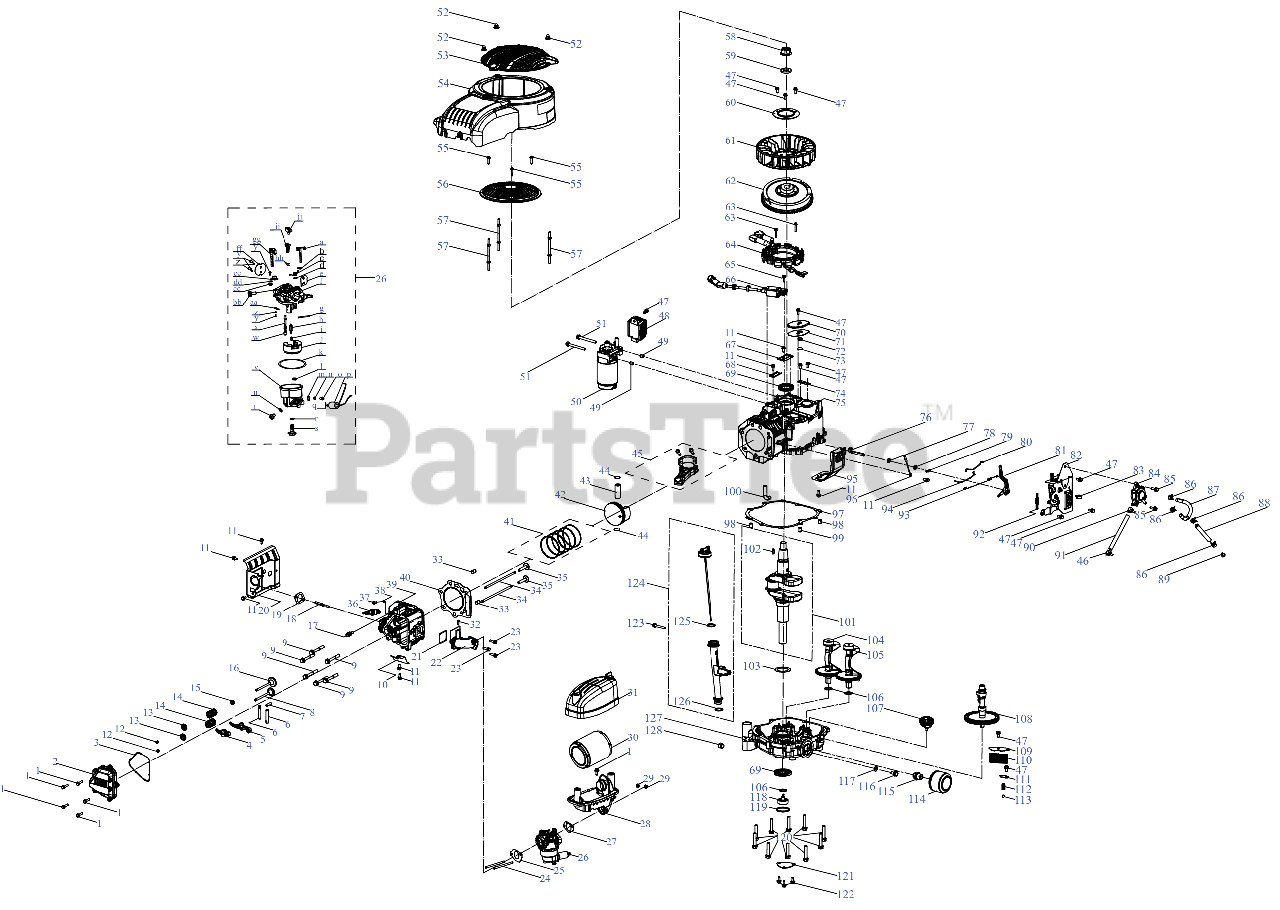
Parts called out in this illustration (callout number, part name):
1	BOLT M6-1 x 25 GR8.8
2	VALVE COVER
3	VALVE COVER GASKET
4	ROCKER ARM (EXHAUST)
5	ROCKER ARM (INTAKE)
6	ROCKER ARM SHAFT
7	CAMSHAFT PIN
8	EXHAUST VALVE
9	BOLT M10-1.25 x 70
11	BOLT M6-1 x 12 GR8.8
12	VALVE CAP
13	VALVE SPRING SEAT
14	VALVE SPRING
15	INTAKE VALVE SEAL
16	INTAKE VALVE
19	EXHAUST GASKET
20	SHROUD - LEFT SIDE
21	INTAKE PIPE RING
22	INTAKE PIPE
23	BOLT M6 x 22
24	STUD M6-1.00 x 92
25	INTAKE GASKET
26	CARBURETOR ASSEMBLY HY-8X90
27	AIR FLTER GASKET
28	INTAKE MANIFOLD
30	AIR FILTER W/PREFILTER
31	AIR FILTER COVER
32	SELF TAPPING SCREW 4.8 x 16
34	SINGLE PUSH ROD
36	SPARK PLUG
37	BOLT M5-.8 x 10
38	FLAT WASHER: 5.3 x 10 x 1
39	CYLINDER HEAD
40	CYLINDER HEAD GASKET
41	PISTON RING SET
43	PISTON PIN
44	PISTON PIN SNAP RING
45	CONNECTING ROD ASSEMBLY
47	BOLT M6-1 x 14 GR8.8
48	REGULATOR ASSEMBLY
50	ELECTRIC STARTER
51	BOLT M8-1.25 x 80
52	ACORN NUT
53	SHROUD SCREEN COVER
54	ENGINE SHROUD
54	SHROUD SPACER
55	BOLT 5.5 x 25
56	DEBRIS SHIELD
58	NUT M20 x 1.5
59	WASHER 20.5 x 5 x 40
60	VANE PLATE
61	COOLING FAN
63	BOLT M5 x 28
64	CHARGING COIL
65	BOLT-M6-1 x 28 GR8.8
66	IGNITION COIL ASSEMBLY
67	WIRE PLATE
68	BREATHER SCREEN
69	OIL SEAL 38 x 58 x 8
70	BREATHER COVER
71	BREATHER COVER GASKET
72	BREATHER VALVE SPRING
73	BREATHER VALVE
75	CRANKCASE
76	GOVERNOR GEAR SHAFT
77	WASHER 8 x 0.8 x 16
78	GOVERNOR SEAL
79	GOVERNOR SHAFT CLIP
80	CHOKE LINKAGE
81	GOVERNOR LEVER
82	THROTTLE BRACKET ASSEMBLY
83	FUEL LINE SUPPORT CLAMP
85	BOLT M6-1 x 18 GR8.8
86	HOSE CLAMP
87	BREATHER HOSE
88	FUEL HOSE (6.3 x 12.5 x 100)
91	FUEL HOSE (6.3 x 12.5 x 180)
92	GOVERNOR SPRING
93	THROTTLE LINKAGE SPRING
94	THROTTLE LINKAGE
95	SHROUD - RIGHT
96	GROUND WIRE CONNECTION
97	CRANKCASE COVER GASKET
98	DOWEL PIN
99	DOWEL PIN
100	VENTING HOSE
101	CRANKSHAFT ASSEMBLY
102	FLYWHEEL KEY
103	WASHER 38.3 x 54 x 1
104	BALANCE SHAFT (LH)
105	BALANCE SHAFT (RH)
106	WASHER 17.2 x 26 x 1
107	GOVERNOR GEAR ASSEMBLY
109	FILTER COVER
110	FILTER SCREEN
111	PRESSURE RELEASE COVER
112	PRESSURE RELEASE SPRING
113	OIL PUMP STEEL BALL
114	ENGINE OIL FILTER
115	SCREW JOINT OIL FILTER ADAPTER
116	BOLT M8 x 15
117	OIL DRAIN PLUG WASHER
118	OIL PUMP ASSEMBLY
120	BOLT M8 x 45
121	OIL SEPARATOR
122	SCREW M6-1 x 16
123	BOLT M6-1 x 45 CL5.8
124	DIPSTICK ASSEMBLY
127	CRANKCASE COVER W/GOVERNOR
128	ENGINE PLUG 3/8 NPT
